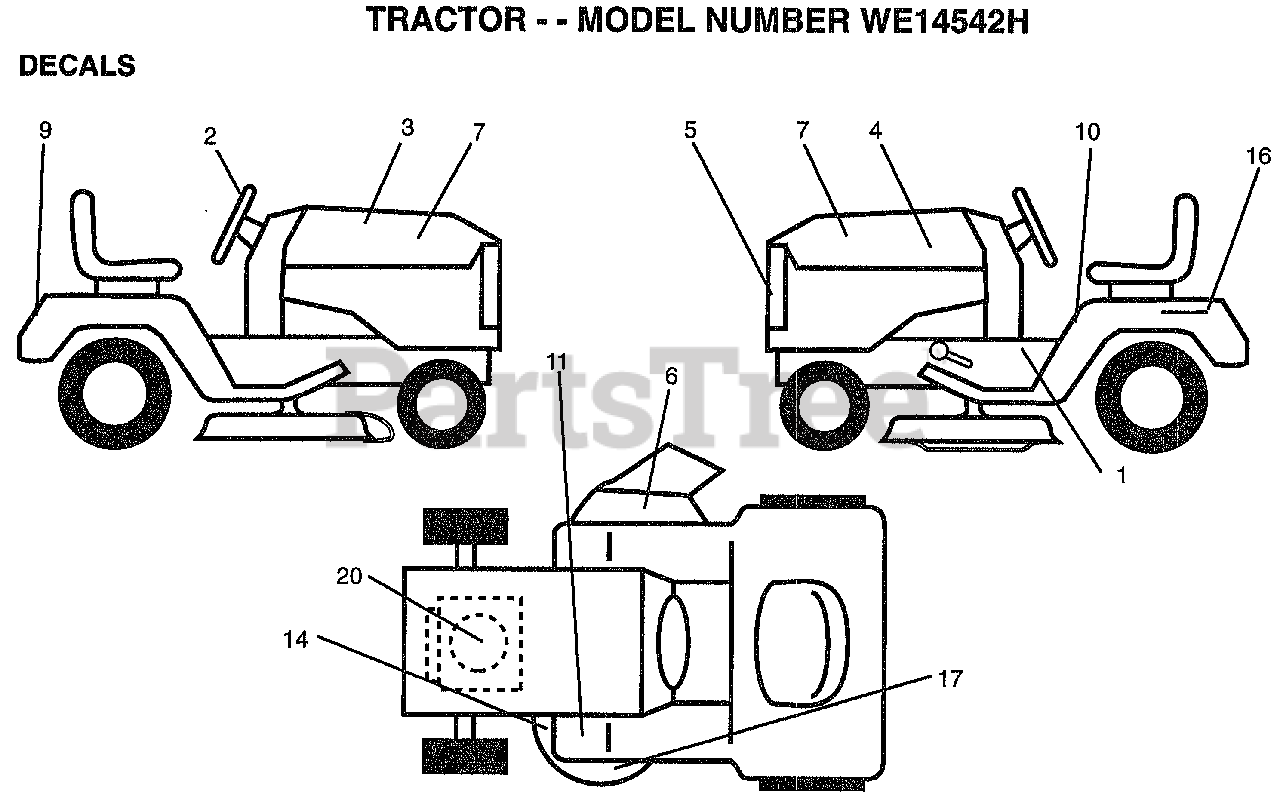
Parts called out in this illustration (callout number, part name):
1	"DECAL.OPER,SDL"
2	DECAL, INS STRG WH
3	DECAL.HOOD.RH.
4	DECAL.HOOD.LH
5	DECAL, GRILLE LENS
6	"DECAL, WARNING"
7	DECAL PANEL SIDE
9	DECAL.FENDER.LOGO
10	DECAL.CAUT.ENG/FR
11	DECAL T
14	"DECAL-SCHEM,BELT"
16	DECAL.BATRY.3-3908
17	DECAL, DECK GRASSEATER
20	DECAL, ENGINE
